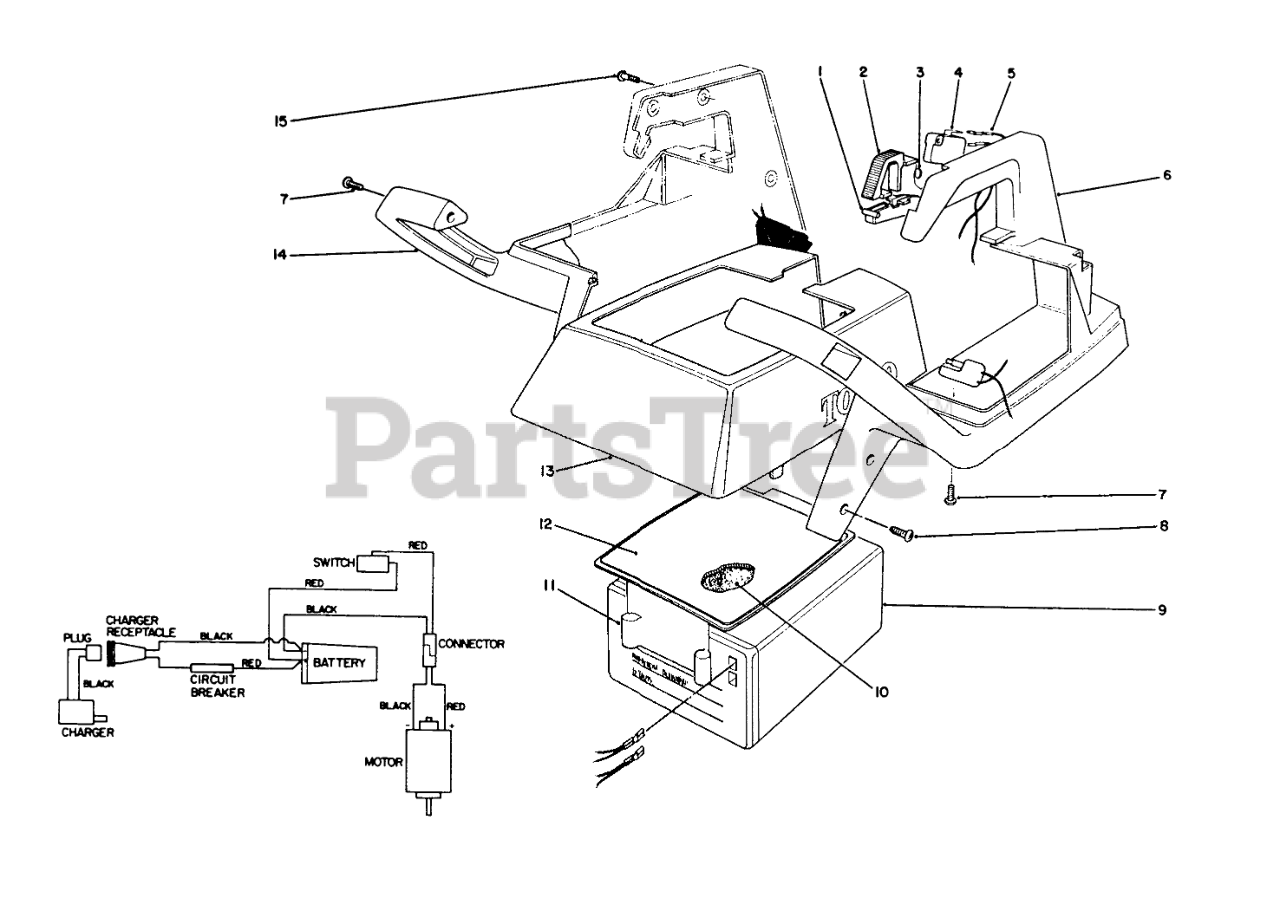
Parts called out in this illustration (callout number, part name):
1	TRIGGER
2	TRIGGER LOCK
3	SPRING
4	Switch
5	Wiring Harness
6	LH BATTERY CASE/HNDL
7	Screw
8	10-16 X .31 SCREW
9	BATTERY
10	FOAM PAD
11	CONTROL PANEL, CL-710
12	DECAL, FRONT PANEL, CSA
13	Cover
14	RH BATTERY CASE/HNDL
15	SCREW-PPH
